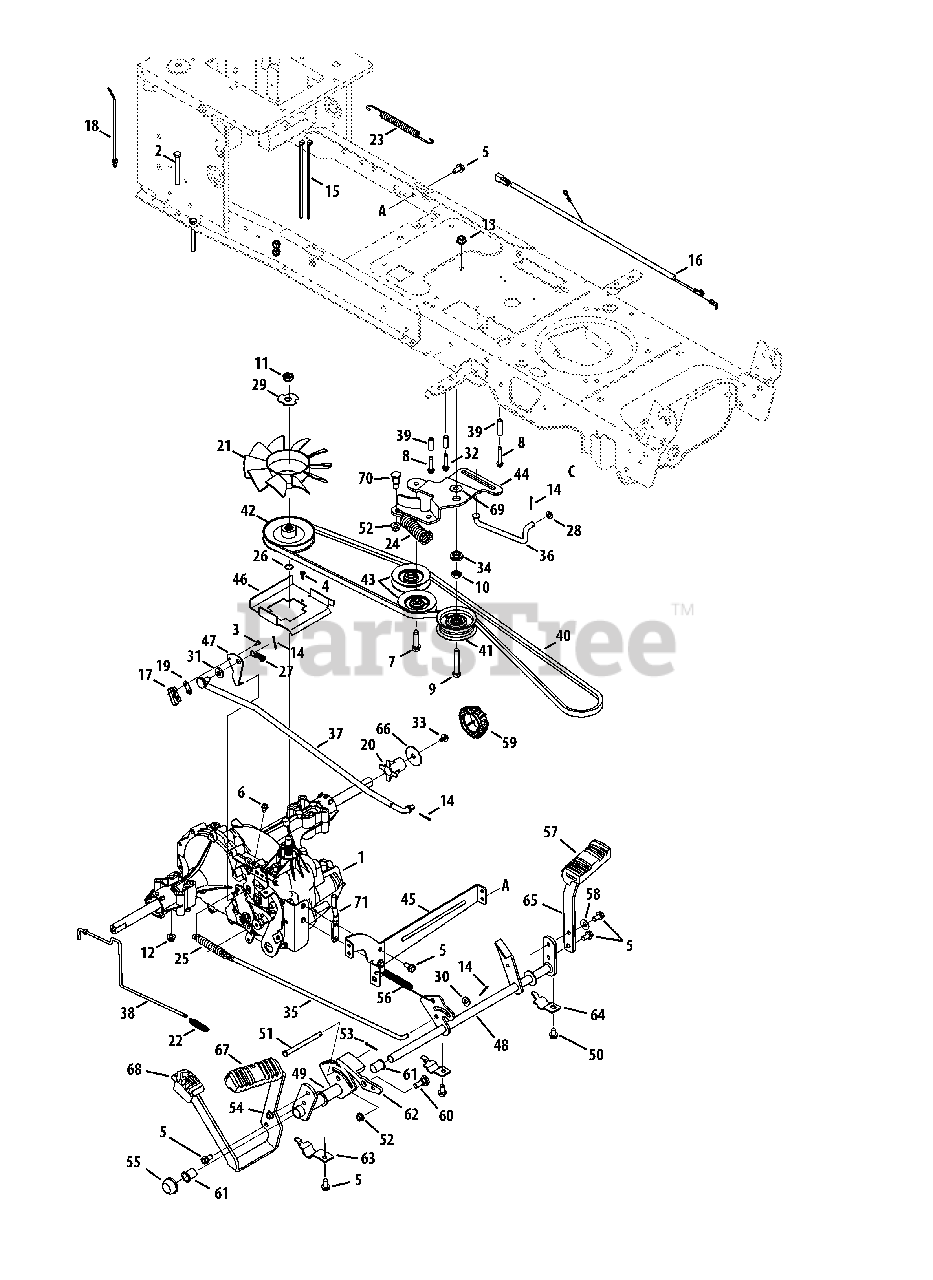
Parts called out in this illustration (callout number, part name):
1	Transmission, Hydro-Gear 0510
2	Hex Screw, 5/16-18, 2.75, Gr5, Std
3	Screw, #8-18, 0.500,
4	Screw, #10-16, 0.500
5	Screw, Self-tapping, 5/16-18, .750
6	Screw, Self-tapping, 1/4-20, 0.375
7	Screw, Self-tapping, 3/8-16, 1.500
8	Screw, Self-tapping, 1/4-20, 1.625
9	Hex Screw, 3/8-16, 2.25, Gr5
10	Nut, Jam, 7/16-20, Gr2
11	Nut, Jam Lock, 1/2-20, Gr5, Nylon
12	Nut, Flange Lock, 5/16-18, Nylon
13	Nut, Flange Lock, 3/8-16
14	Pin, Cotter, 3/32, 1.0
15	Cable, Tie, 3/16 x .05 x 7.4
16	Jumper Harness, Ground & Reverse
17	Switch, Spring, Short
18	Tie, Cable, Push Mount 7.5
19	Plate, Insulator Nut
20	Sleeve, .765 Id x 1.500
21	Fan, Hydro
22	Spring, Extension, .48 Od x 2.03
23	Spring, Extension, .500 Dia x 12.6
24	Spring, Extension, 1.00 Dia x 4.75
25	Spring, Extension, .59 Od x 4.00
26	Ring, Wire
27	Spring, Extension, .375 Od x 1.44
28	Washer, Flat, .330 x .630 x .0635
29	Washer, Lock, Transmission Hydro
30	Washer, Flat, .344 x .750 x .120
31	Washer, Flat, .407x.812x.135, Ht
32	Screw, Self-tapping, 1/4-20 x 1.75
33	Screw, 5/16-24 x .750
34	Spacer, Shoulder, 1.375 x .380 x .183
35	Rod, Brake, LT Hydro
36	Rod, Transmission, Bypass
37	Rod, Control, Hydro
38	Rod, Hydro Bypass
39	Spacer, .260 x .372 x 1.420
40	Belt, V-Type
41	Pulley, Idler, Flat 2.75 OD
42	Pulley, Input, 4.13 Dia
43	Pulley, Idler, V-Type x 3.06
44	Bracket, Idler, Center Double
45	Bracket, Mount, Hydro
46	Bracket, Support, Belt Disengage
47	Bracket, Actuator, Switch
48	Control Assembly, Brake
49	Bracket Assembly, Pedal, Hydro
50	Screw, Self-tapping, 5/16-18, 0.625,
51	Pin, Clevis, 5/16 x 3.985
52	Nut, Flange Lock, 3/8-16, Nylon
53	Pin, Cotter, Bow-Tie 72
54	Bracket, Pedal, Hydro
55	Cap, Push 5/8
56	Spring, Extension, .63 Dia x 4.95
57	Pad, Pedal, Brake
58	Washer, Bell, .340 x .872 x .060
59	Cap, Hub
60	Bolt, Shoulder, .500 x .270, 3/8-16
61	Bearing, Flange, .630 x .695 x .60
62	Latch, Cruise
63	Bracket, Support, Pedal Strap
64	Bracket, Support, Pedal Strap 5/8
65	Bracket, Pedal, Brake
66	Washer, Flat, .350 x 1.59 x .062
67	Pad, Pedal, Forward
68	Pad, Pedal, Reverse
69	Wash, Flat, .385 x 1.00 x .030
70	Scr, Shldr, .50 x .685 3/8-16
71	Belt Keeper Rod
